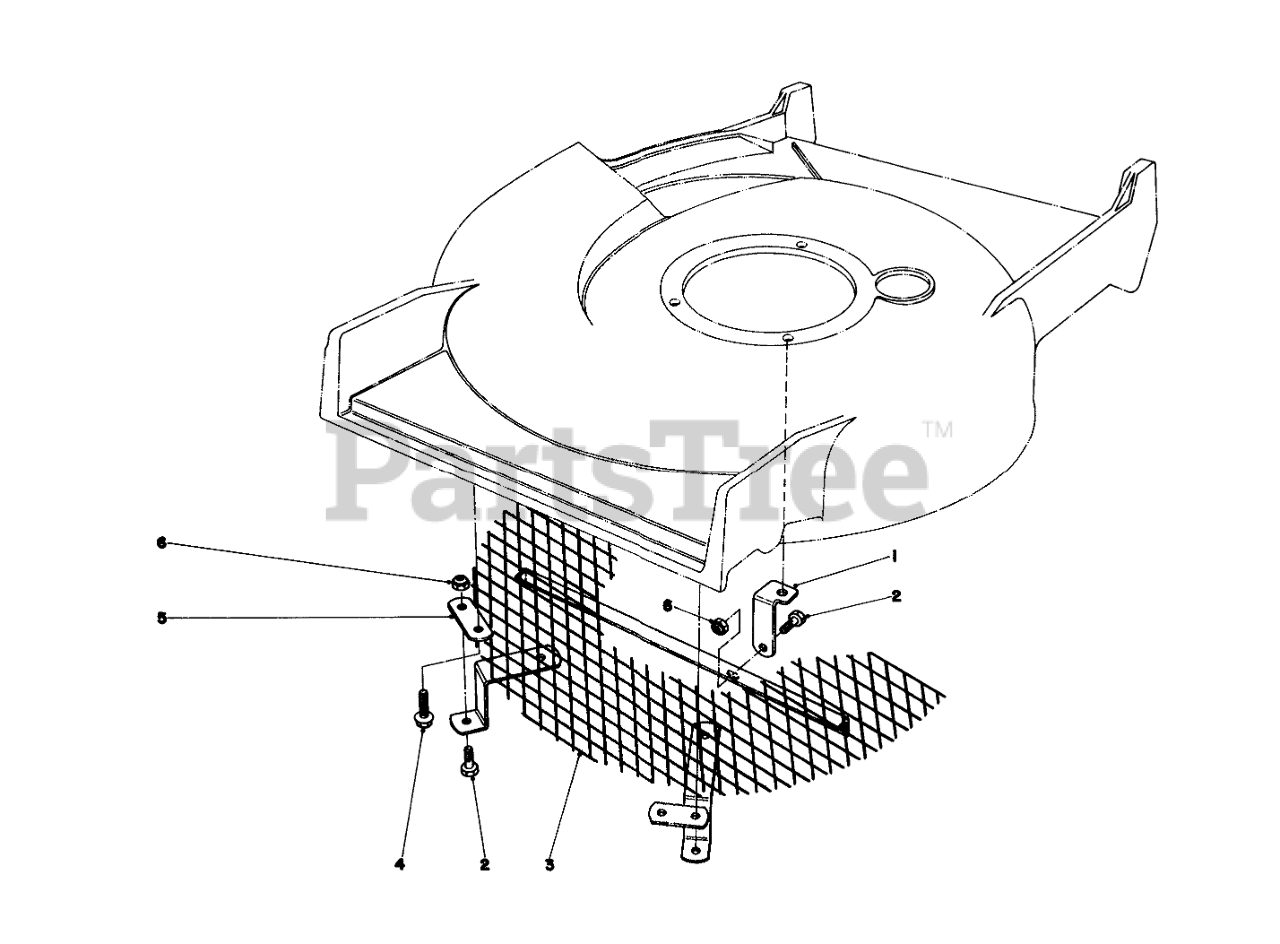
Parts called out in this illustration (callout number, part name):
1	Support Bracket
2	SCREW-HH
3	Screen
4	SCREW-HWHTF
5	ANCHOR
6	NUT-LOCK, NI
